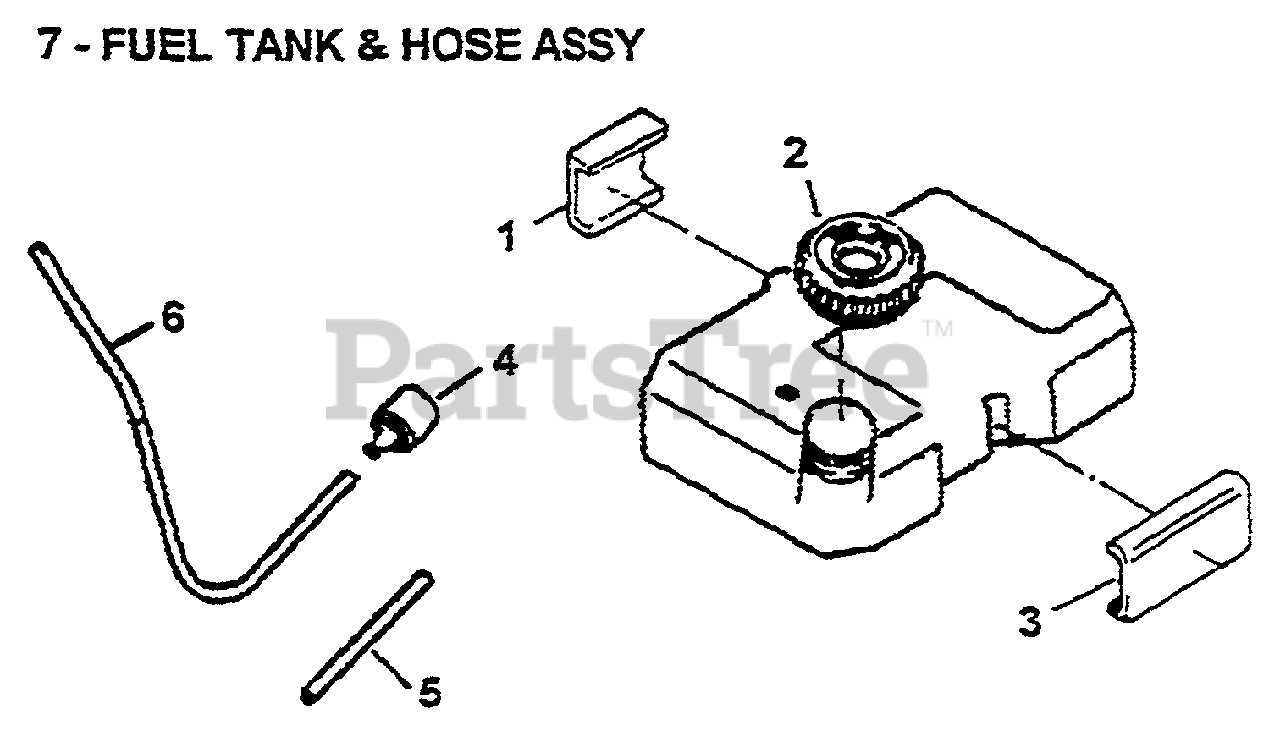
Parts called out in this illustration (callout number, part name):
4	FILTER, FUEL
5	HOSE, FUEL
6	HOSE, FUEL
7	FUEL TANK ASSY
